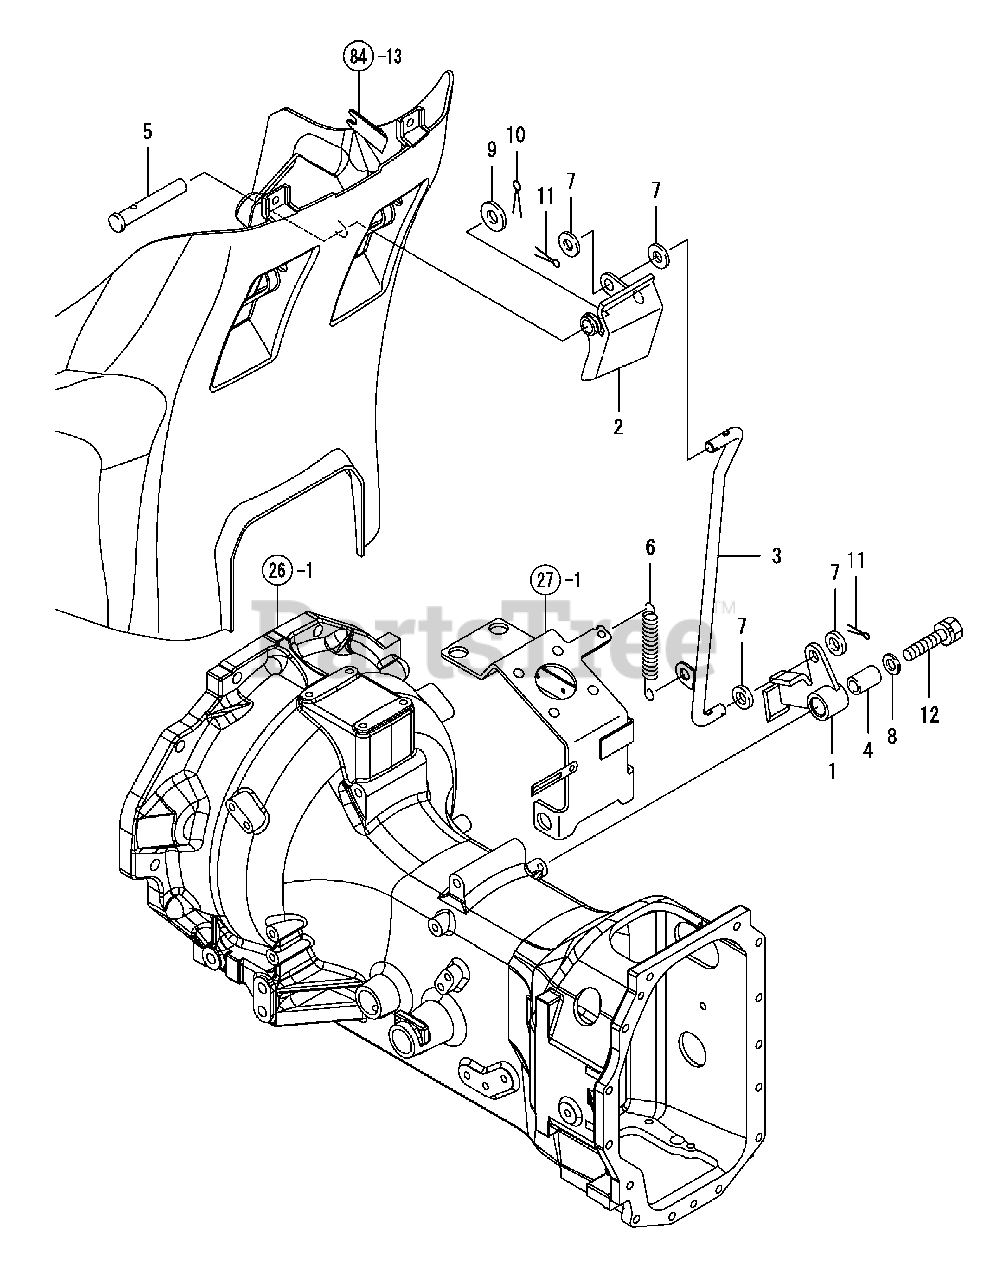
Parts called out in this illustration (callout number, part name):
1	Rachet Cmp, Cruise
2	Lever, Cruise Control
3	Cruise Rod Cmp
7	Washer 10, Polished
8	Washer 10, Polished
9	Washer 12, Polished
10	Cotter Pin 2.0X32
11	Cotter Pin 2.5X25
